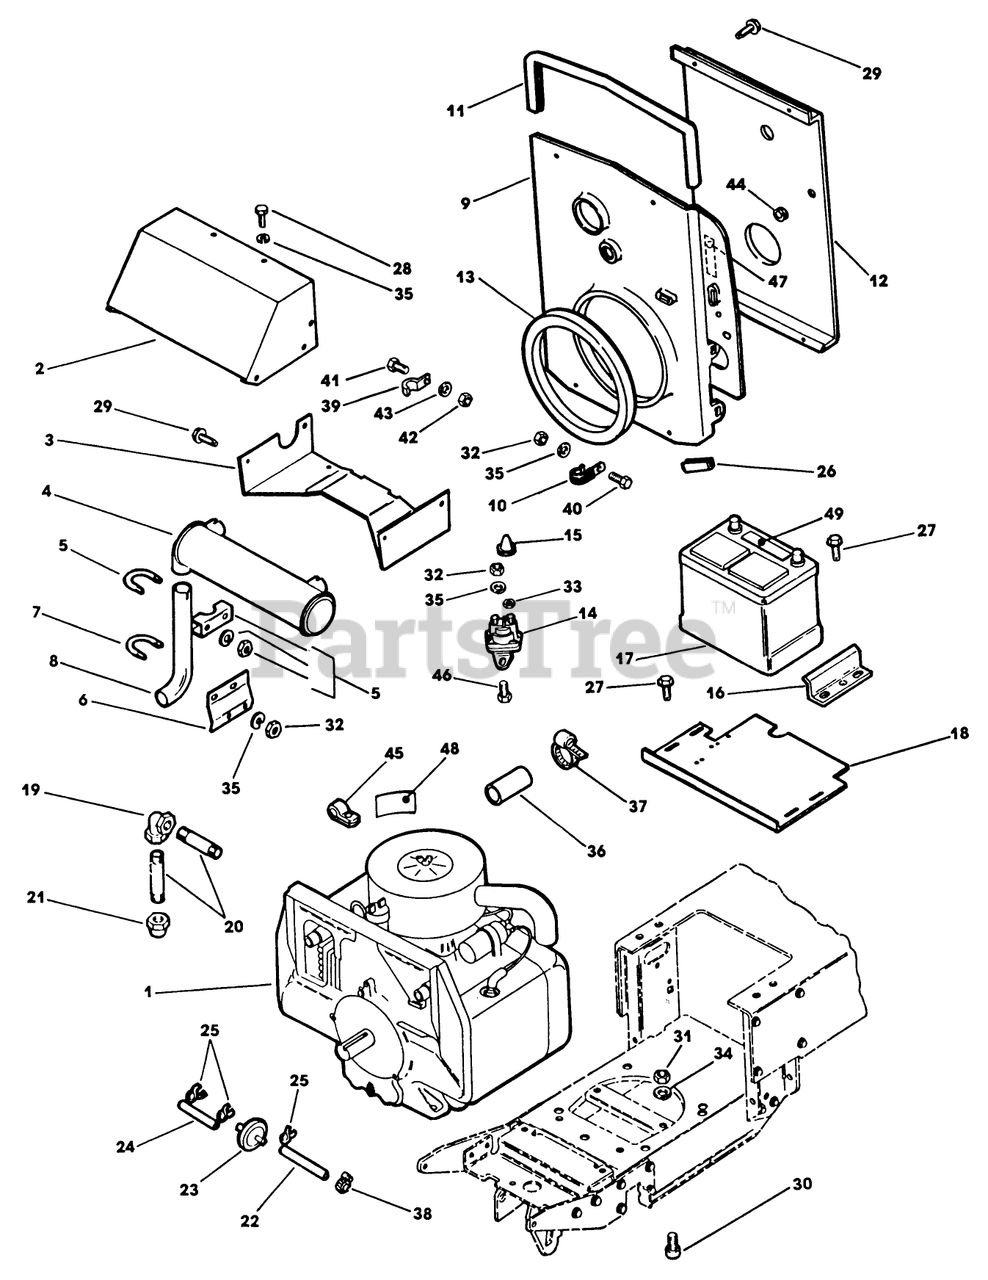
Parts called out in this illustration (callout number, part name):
4	MUFFLER
12	SCREEN - DUST
14	SOLENOID
25	CLAMP
28	SCREW-HH
29	SCREW S
31	NUT
32	NUT
33	NUT-HEX
34	WASHER
37	CLAMP - HOSE
40	SCREW
41	SCREW - HEX
42	NUT SS
